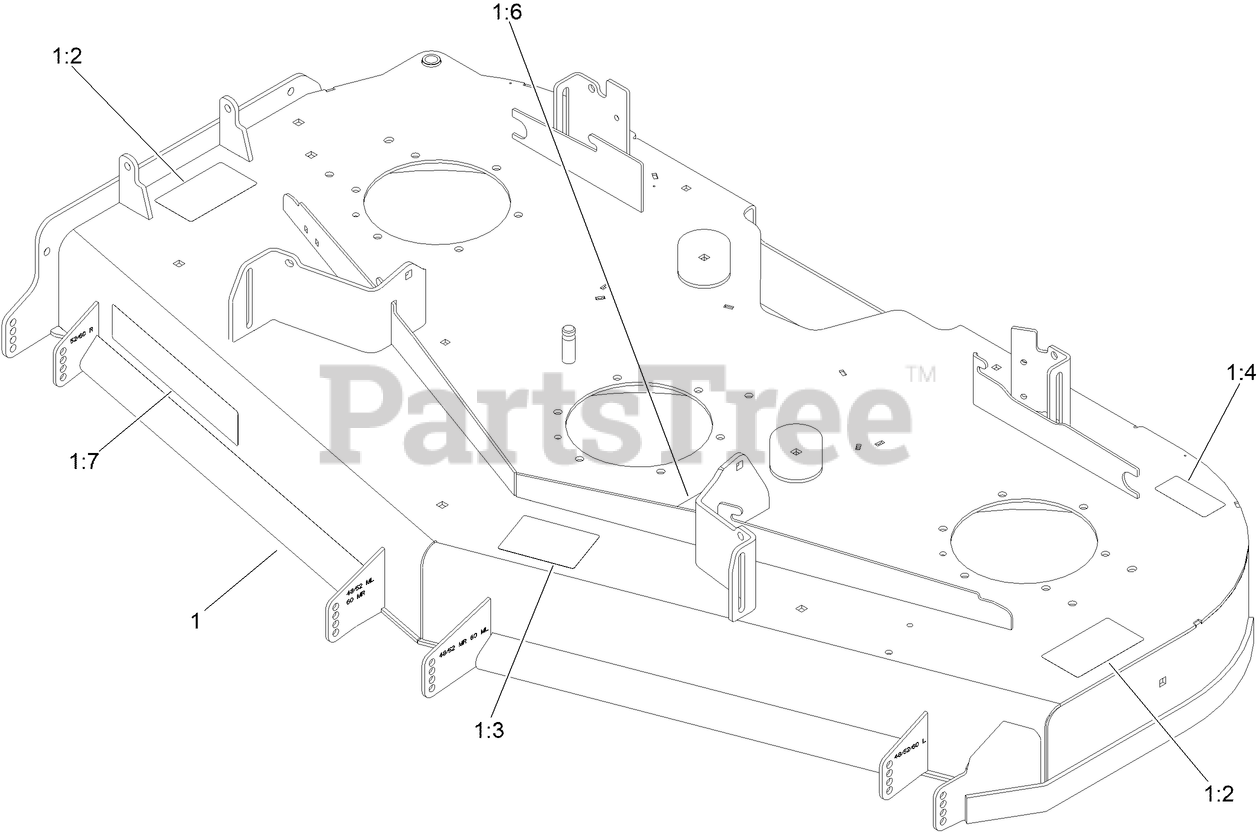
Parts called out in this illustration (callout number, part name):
1:2	DECAL-DANGER
1:3	DECAL-SCALP, ANTI
1:4	DECAL-BOLT TORQUE
1:6	DECAL-ROUTING, BELT
